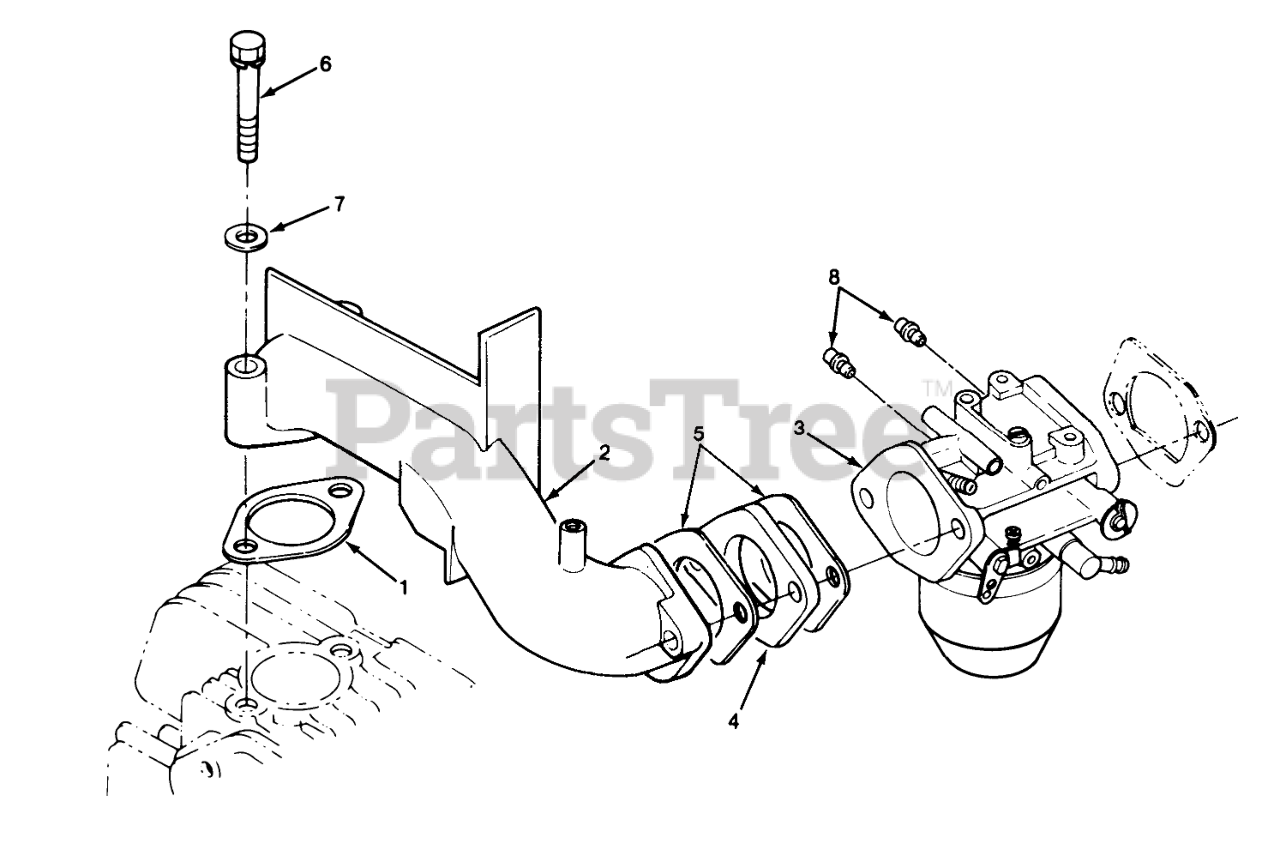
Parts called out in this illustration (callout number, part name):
2	ELBOW-INTAKE
3	CARBURETOR
4	INSULATOR
5	Gasket
6	HHCS-M8 X 50MM
7	Nut-M8
8	Clip
